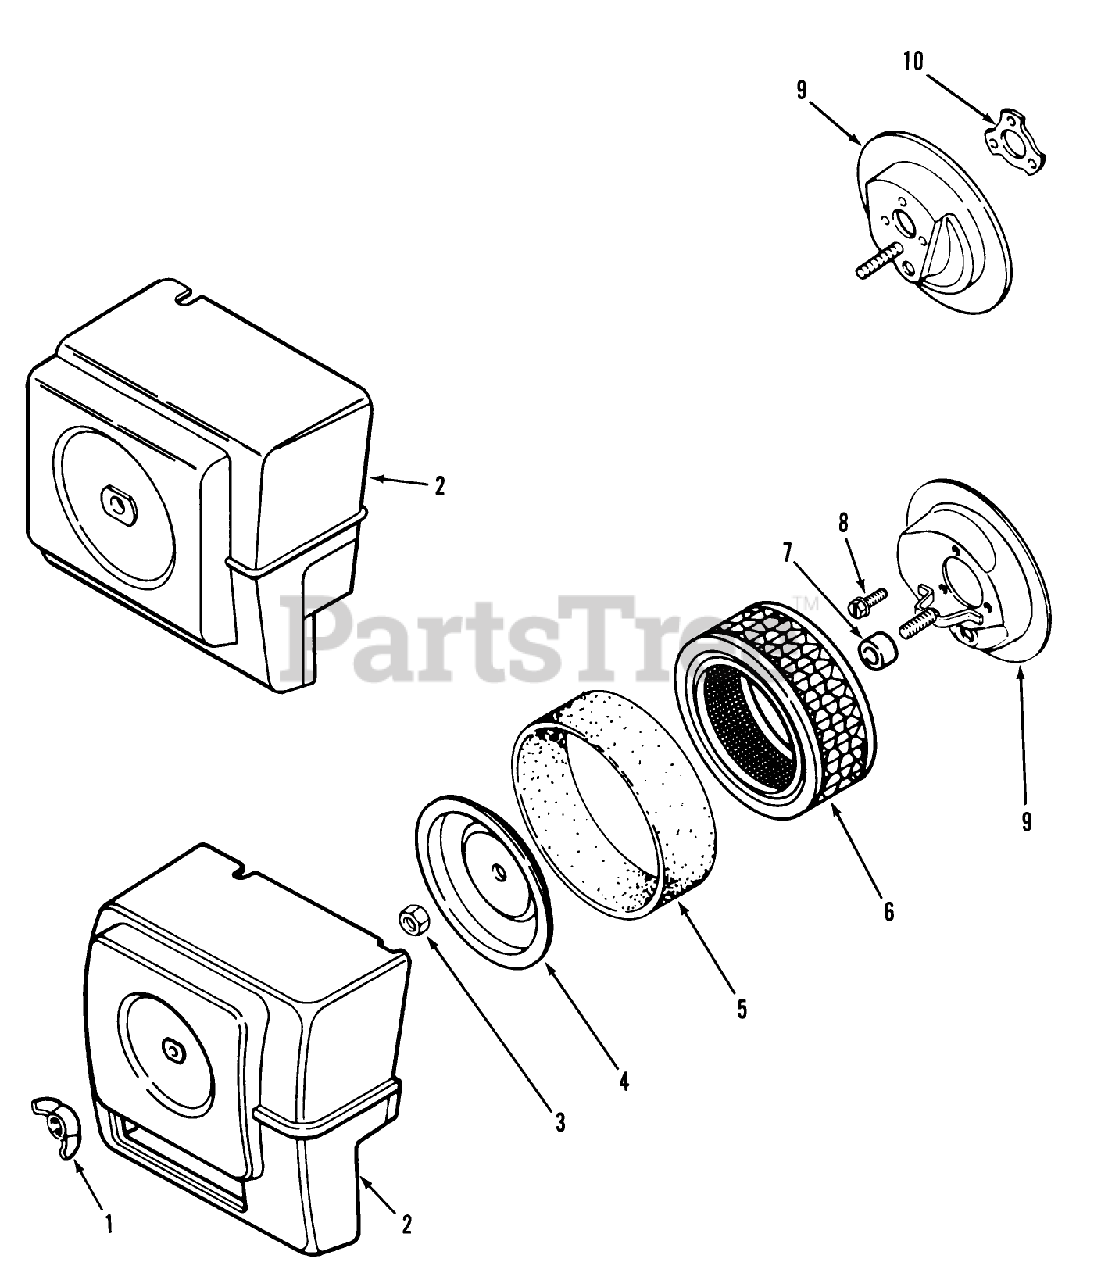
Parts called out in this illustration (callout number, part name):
1	KOHLER X-276-7
2	KOHLER # 41-096-27
3	KOHLER 41-100-04
4	KOHLER 52-082-04
5	KOHLER 41-083-04
6	KOHLER 235116
7	KOHLER 41-032-02
8	KOHLER X-67-59
9	KOHLER 41-094-14
10	KOHLER 41-041-11
